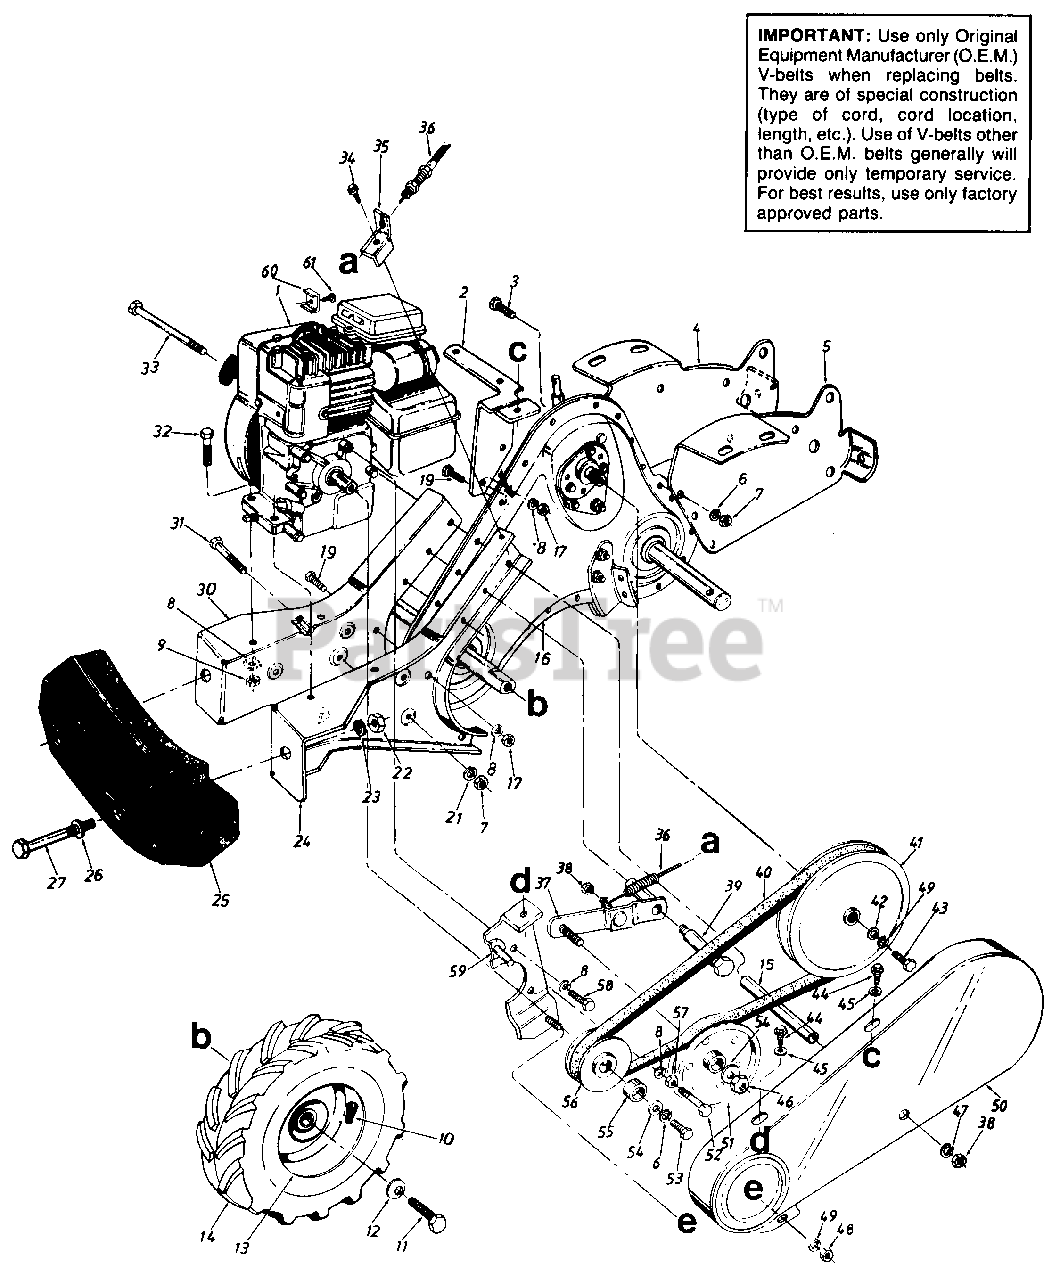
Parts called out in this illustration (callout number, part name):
1	Engine
7	Hex Nut 3/8-16 Thd.
8	L-Wash. 5/16" I.D.
9	Hex Nut 5/16-18" Thd.
10	Air Valve
11	Hex Bolt 5/16-24 x .62" Lg.
12	Bell-Wash. .345" I.D. x .88"
13	Wheel Rim Ass'y. Only
14	L.H. Wheel Ass'y. Comp.
16	Transmission Comp.
17	Hex Nut 5/16-18 Thd.
19	Hex Bolt 5/16-18 x .75" Lg.
21	L-Wash. 3/8" I.D. H.D.
22	Hex Nut 1/2-13 Thd.
23	L-Wash. 1/2" I.D.
26	Fl-Wash. .510" I.D. x 1.0"
27	Hex Bolt 1/2-13 x 5.00" Lg.
32	Hex Bolt 5/16-18 x 1.50"
33	Hex Bolt 5/16-18 x 4.75" Lg. Gr. 2
34	Hex Wash. TT-Tap Scr. 5/16-18 x .62" Lg.
35	Bracket Clutch Cable
36	Clutch Control Cable 53" Lg.
39	Shld. Bolt .500" Dia. x 2.27"
40	"V"-Belt
41	"V"-Pulley Split 5/8" I.D.
42	Fl-Wash. 1/4" I.D. x .93" O.D.
43	Hex Bolt 1/4-28 x .75" Lg.
44	Hex Wash. Hd. S-Tap Scr. 1/4-20 x .50" Lg.
45	Fl-Wash. .281" I.D. x .625"
46	Hex Cent. L-Nut 3/8-24 Thd.
47	Fl-Wash. 5/16" I.D.
48	Hex Nut 1/4-20 Thd.
49	L-Wash. 1/4" I.D.
51	Fl-Idler w/Flanges 3.75" O.D.
52	Hex Bolt 5/16-24 x 1.75
53	Hex Bolt 3/8-24 x 1.00" Lg.
54	Fl-Wash. 3/8" I.D. x 1.00"
55	Spacer .758" I.D. x .990"
56	Engine Pulley
57	Hex Nut 5/16-24 Thd.
58	Hex Bolt 5/16-24 x .62" Lg.
61	Hex Sems Scr. #10-32 x .62"
